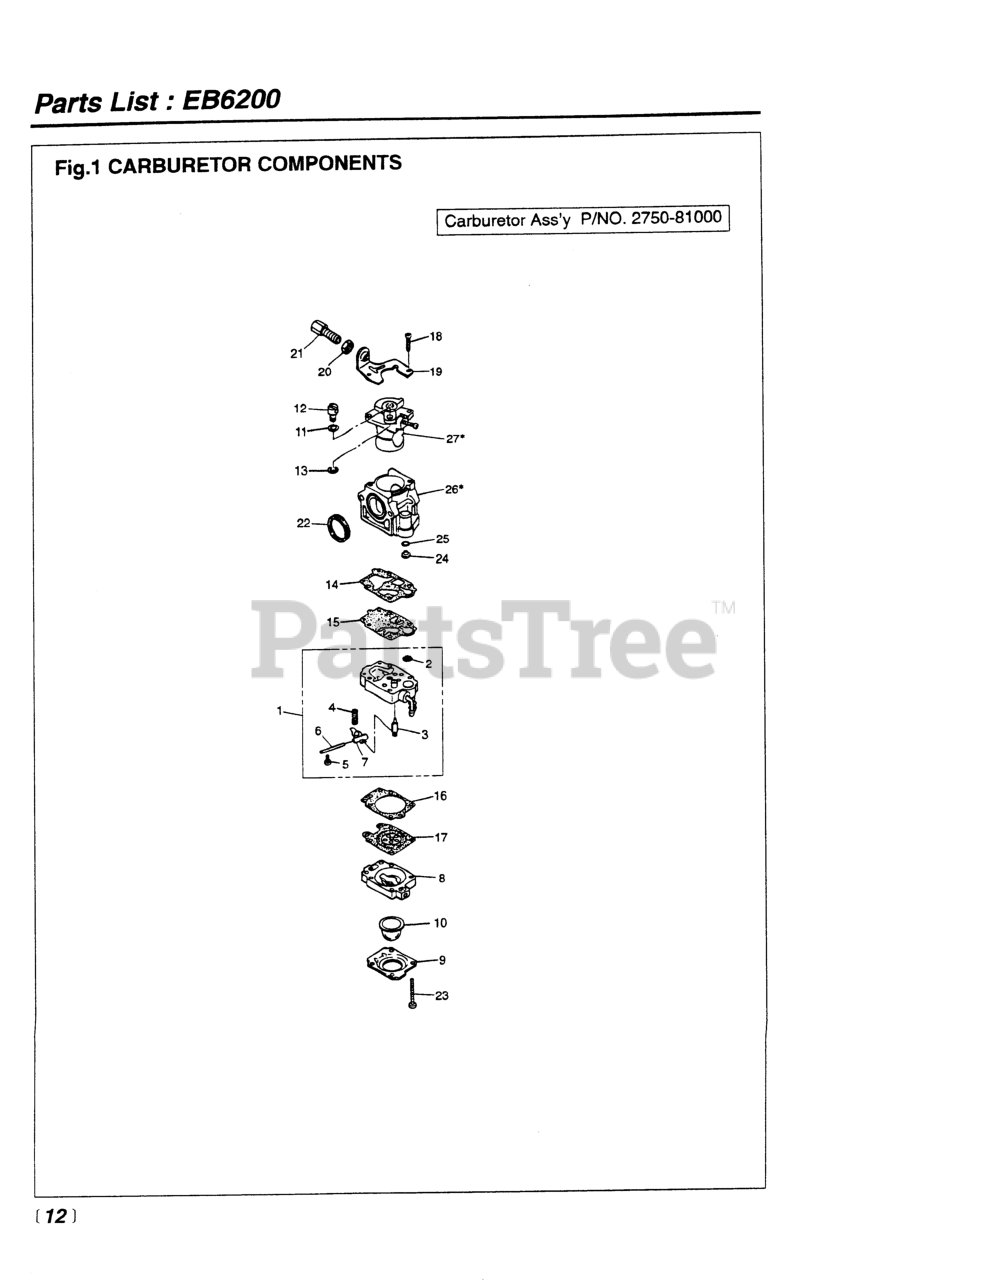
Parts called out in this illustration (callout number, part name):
1	BODY, PUMP
3	VALVE, INLET
4	SPRING, METERING LEVER
5	SCREW, METERING LEVER PIN
6	PIN, METERING LEVER
7	LEVER
8	BODY, PURGE
9	COVER, PUMP
10	PUMP, PRIMING
11	WASHER
12	SWIVEL
13	RING
14	GASKET, PUMP
15	DIAPHRAGM
16	GASKET, DIAPHRAGM
17	DIAPHRAGM (USE 4810-81260)
18	SCREW
20	NUT, CABLE ADJUSTER
21	SCREW, CABLE ADJUSTER
22	RING, PACKING
23	SCREW
24	JET
25	RING, O
26	CARBURETOR (WYK-73-1)
27	CARBURETOR (WYK-73-1)
